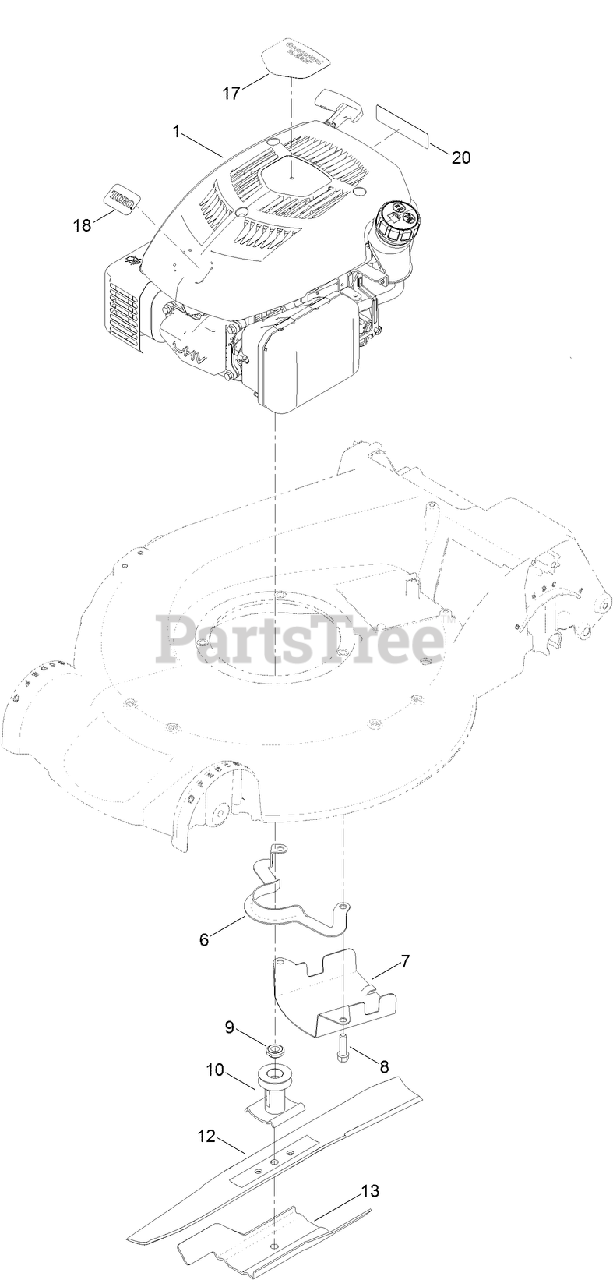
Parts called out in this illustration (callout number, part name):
1	ENGINE-1P65F-2
6	GUIDE-BELT
7	SHIELD-GRASS
8	SCREW-TAPTITE
9	Spacer-Driver
10	DRIVER-BLADE
12	BLADE-RECYCLING
13	Accelerator-Blade
17	DECAL-SHROUD
20	DECAL-ARRESTER, SPARK
